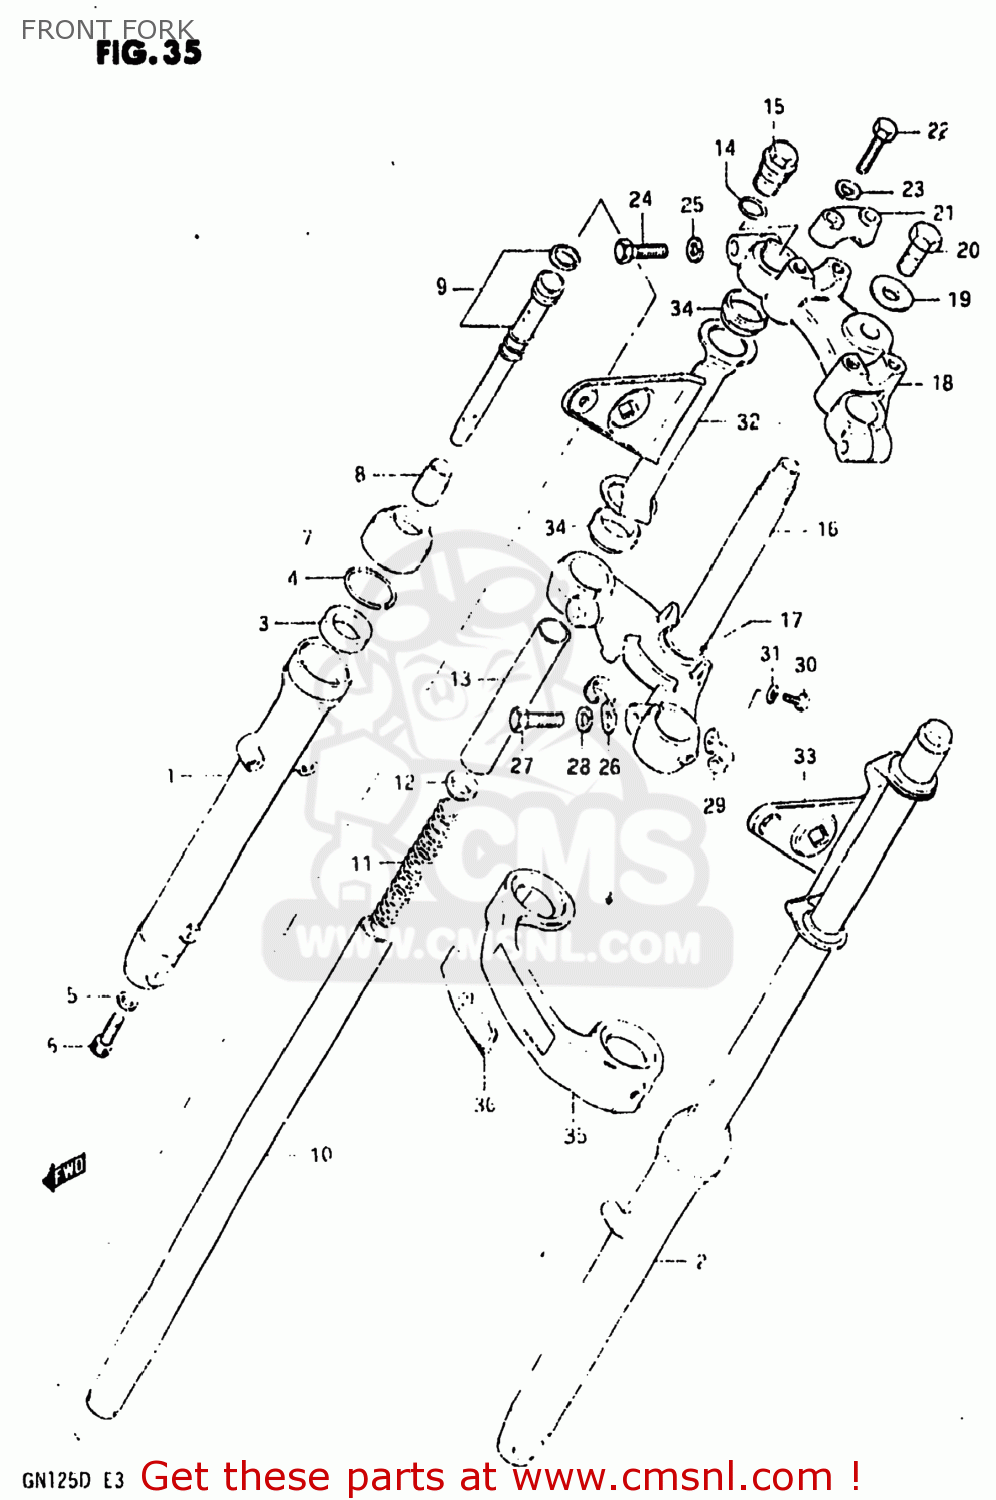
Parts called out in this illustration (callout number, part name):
1	TUBE,OUTER,R
2	TUBE,OUTER,LEFT
3	SEAL,OIL
4	RING,SNAP
5	GASKET (NAS)
6	BOLT,FORK CYLINDER(10X25)
7	SEAL,DUST
8	PIECE,OIL LOCK
9	CYLINDER
10	TUBE,INNER
11	SPRING
12	GUIDE,SPRING COVER
13	SPACER
14	O-RING,FORK INNER TUBE
15	CAP
16	STEM,STEERING
17	RACE,STEERING OUTER LWR
18	HEAD,STEERING STEM(BLACK)
19	WASHER,STEM HEAD(10.5X30X3.2)
20	BOLT,FORK INNER TUBE
21	HOLDER,HANDLE(BLACK)
22	BOLT
23	LOCK WASHER
24	BOLT,FORK INNER TUBE F
25	LOCK WASHER
26	CLIP
27	BOLT,FR FORK LWR(12X33)
28	WASHER,LOCK 12
29	CLIP,BRAKE CABLE
30	SCREW
31	LOCK WASHER
32	BRACKET,HEADLAMP,R
33	BRACKET,HEADLAMP,L
34	CUSHION,HEADLAMP BRACKET
35	COVER,FRAME HEAD
36	EMBLEM,FR FORK COVER
